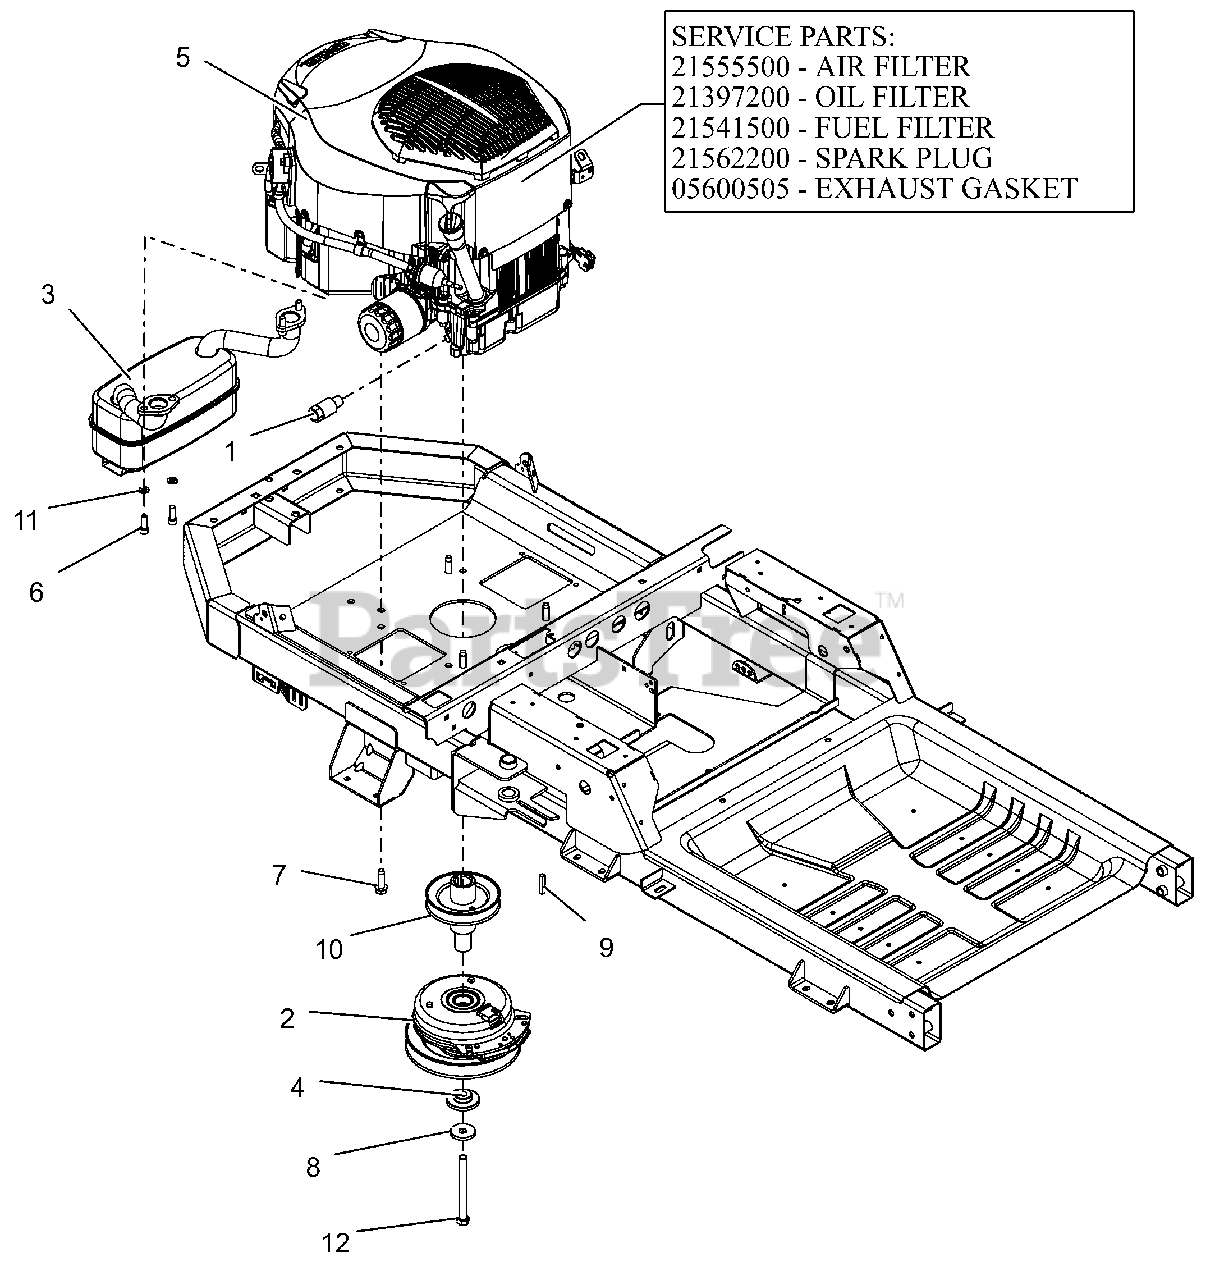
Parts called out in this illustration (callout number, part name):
1	DRAIN, OIL
2	CLUTCH,105FTLB MONOPOLE 6.83"
3	MUFFLER - KOHLER
4	BSHG-FLG .469X1.06X.574X2.0
5	ENGINE, KOHLER 22HP TWIN
5	AIR CLEANER, KOHLER
5	FILTER, OIL - KOH CV20
5	FILTER, FUEL
5	PLUG, SPARK (RFI)
5	GASKET, MUFFLER KOHLER TWIN
6	SCR, SKH .312-18X.875 GR8 ZCC
7	SCR,TAP .375-16X1.25HWH TR ZCC
8	WASHER, 7/16" SPRING DISK
9	KEY-SQ .25 X 1.25 X .25 SAE
10	WLDMT, DRIVE SHEAVE-X
11	WSHR,LK-REG .312X.078 ZCC
12	BLT, HEX .44-20X4.50 G8 ZCC NT
